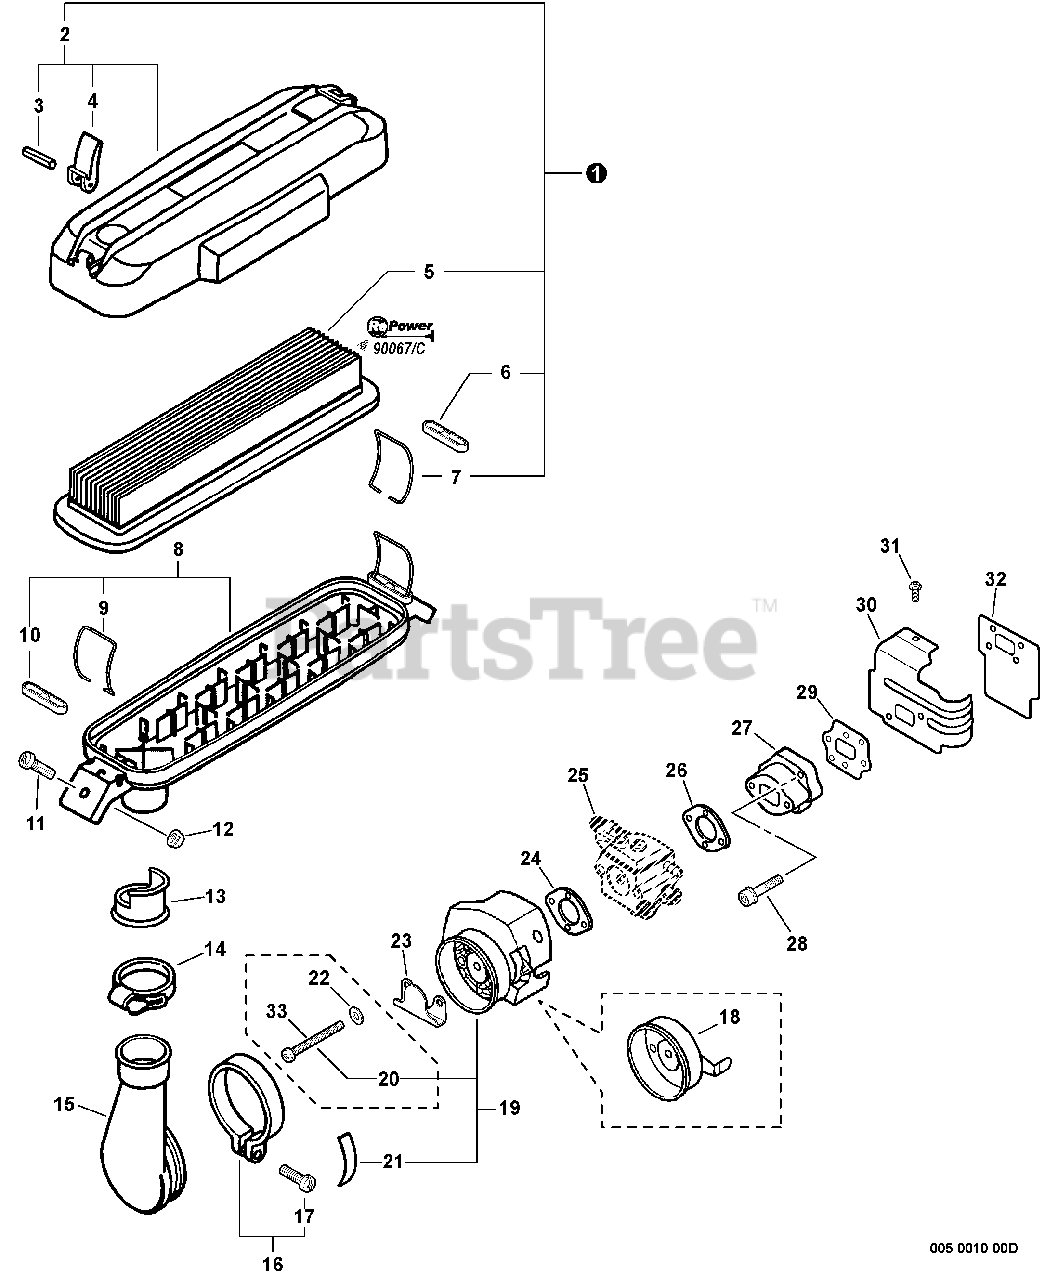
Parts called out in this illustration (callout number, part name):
1	AIR FILTER KIT
2	COVER ASSY, AIR FILTER
3	PIN, SPRING 3×25
5	FILTER, AIR
8	CASE ASSY, AIR FILTER
11	SCREW 5×14
12	NUT, FLANGE M5
13	COLLAR 27
15	ADAPTOR, INTAKE
16	CLAMP KIT
17	SCREW 5×25
19	BRACKET KIT, AIR FILTER
20	SCREW 5×57
21	LABEL, CHOKE
22	WASHER 6.5×13×1
23	PLATE, PREVENT
24	GASKET, INTAKE
25	CARBURETOR
26	GASKET
27	INSULATOR, INTAKE
28	BOLT 5×25
29	GASKET, INTAKE
30	COVER, CYLINDER
31	SCREW 5×10
32	HEAT SHIELD, INTAKE
33	SCREW 5×50
34	TUNE-UP KIT
